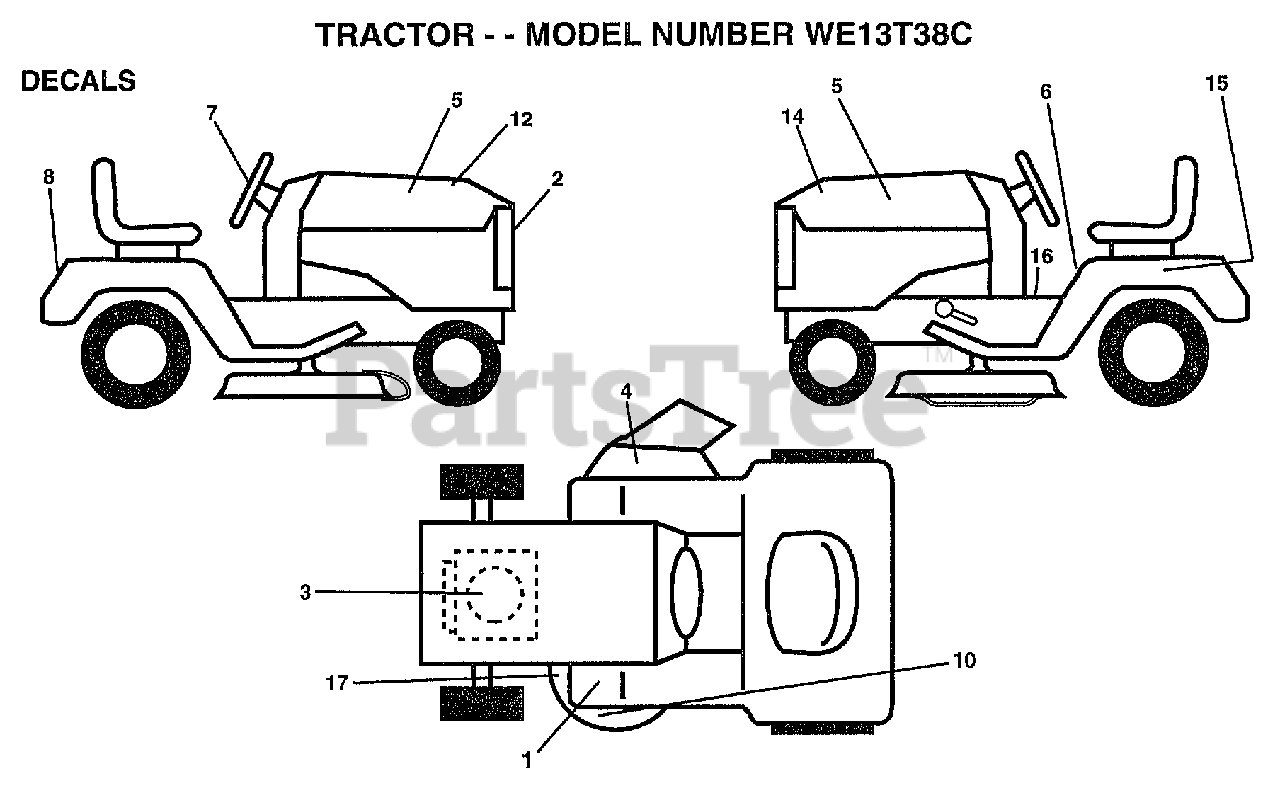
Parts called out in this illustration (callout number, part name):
1	DECAL T
2	DECAL, GRILLE LENS
3	DECAL HP ENGINE
4	"DECAL, WARNING"
5	DECAL.PNL.SD
6	DECAL.CAUT.ENG/FR
7	DECAL, INS STRG WH
8	DECAL.FENDER.LOGO
10	DECAL, DECK GRASSEATER
12	DEECAL.HOOD.RH
14	DECAL.HOOD.LH
15	DECAL.BATRY.3-3908
16	"DECAL.OPER,SDL"
17	DECAL
